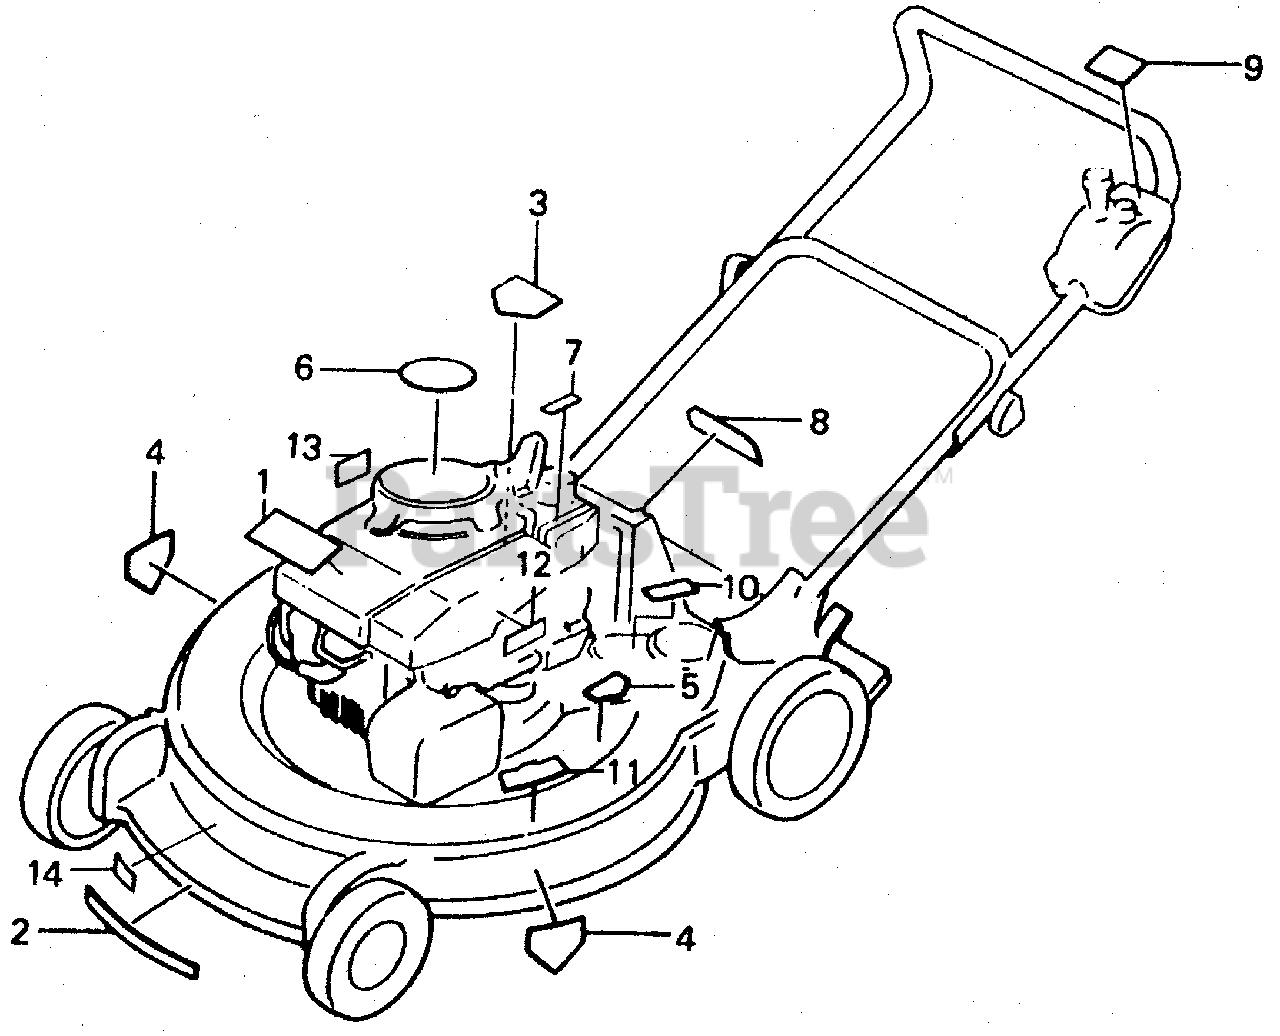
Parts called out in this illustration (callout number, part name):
1	MARK, TOP COVER (NOT AVAILABLE)
2	LABEL A, HOUSING CAUTION (ENGLISH)
3	LABEL C, HOUSING CAUTION
4	LABEL B, HOUSING CAUTION
5	LABEL, STEP POSITION (ENGLISH) (NOT AVAILABLE)
6	CAUTION, OPERATOR (ENGLISH) (NOT AVAILABLE)
7	LABEL, FUEL CAUTION (ENGLISH)
8	LABEL, DISCHARGE GUARD CAUTION (NOT AVAILABLE)
9	LABEL, CONTROL COVER CAUTION (ENGLISH) (NOT AVAILABLE)
10	CAUTION, BELT COVER (ENGLISH) (NOT AVAILABLE)
11	LABEL, PLUG CAUTION (ENGLISH)
12	MARK, AIR CLEANER CAUTION
13	MARK, OIL CAUTION
14	MARK, TYPE (SXM)
